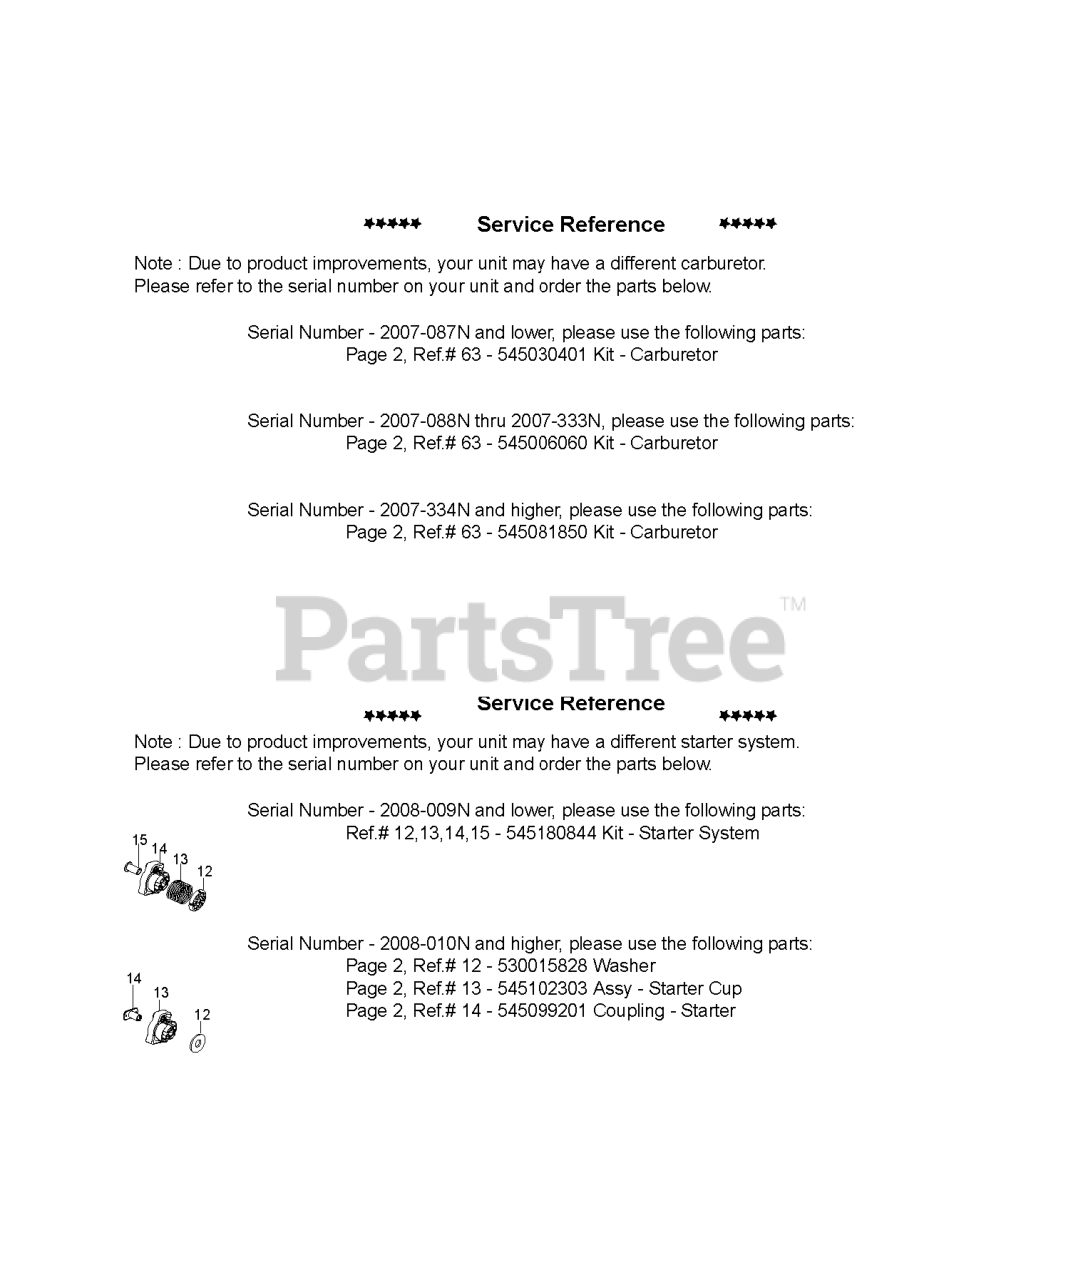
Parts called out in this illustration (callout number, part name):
12	WASHER FLAT
13	ASSY STARTER CUP
14	COUPLING-STARTER
63	CARBURETOR
63	CARBURETOR KIT W38
63	KIT CARBURETOR
